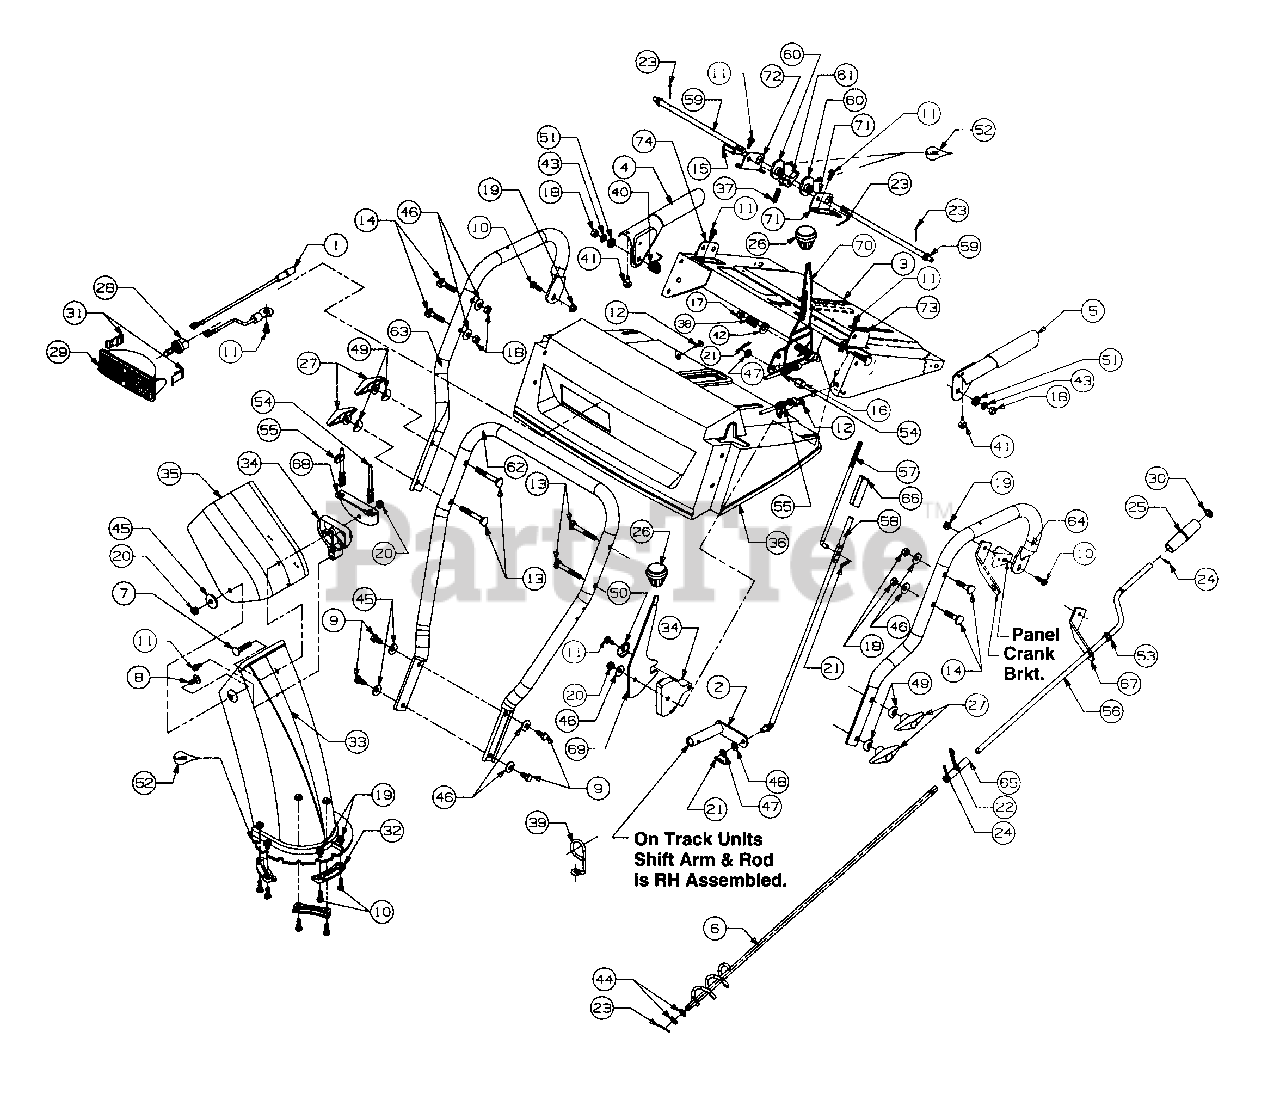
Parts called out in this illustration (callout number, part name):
1	Harness-Light
5	Handle-Engagement - L.H.
8	Bolt-Carriage
9	Screw-Hex
10	Screw-Hex
11	Screw-Washer Head-Hex
12	Screw-Hex
13	Bolt-Carriage
14	Bolt-Carriage
15	Pin-Clevis
16	Ferrule
17	Nut-Hex Lock
18	Nut-Hex
19	Nut-Hex Lock
20	Nut-Hex Lock
21	Pin-Cotter Internal
22	Pin-Cotter
23	Pin-Cotter
24	Pin-Roll
25	Knob-Chute Crank
26	Knob-Shift
27	Knob-Wing Nut
28	Lamp
29	Housing-Lamp
30	Cap-Push
31	Clip-Retaining
32	Keeper-Chute
33	Chute-Lower
34	Guide-Cable
35	Chute-Upper
36	Panel-Handle
37	Spring
38	Spring
39	Wire-Control
40	Spring
41	Bumper
42	Washer-Bell
43	Washer-Lock
44	Washer-Flat
45	Washer
46	Washer-Bell
47	Washer-Flat
48	Washer-Lock
49	Washer-Saddle
50	Washer
51	Washer
52	Lubricant
53	Bushing-Plastic
54	Cable-Chute Control
55	Cable-Chute Control
56	Crank-Chute
57	Rod-Shift Upper
58	Rod-Shift Lower
59	Rod-Cam
60	Cam-Handle Lock
61	Pawl-Handle Lock
66	Connector
70	Handle-Shift
